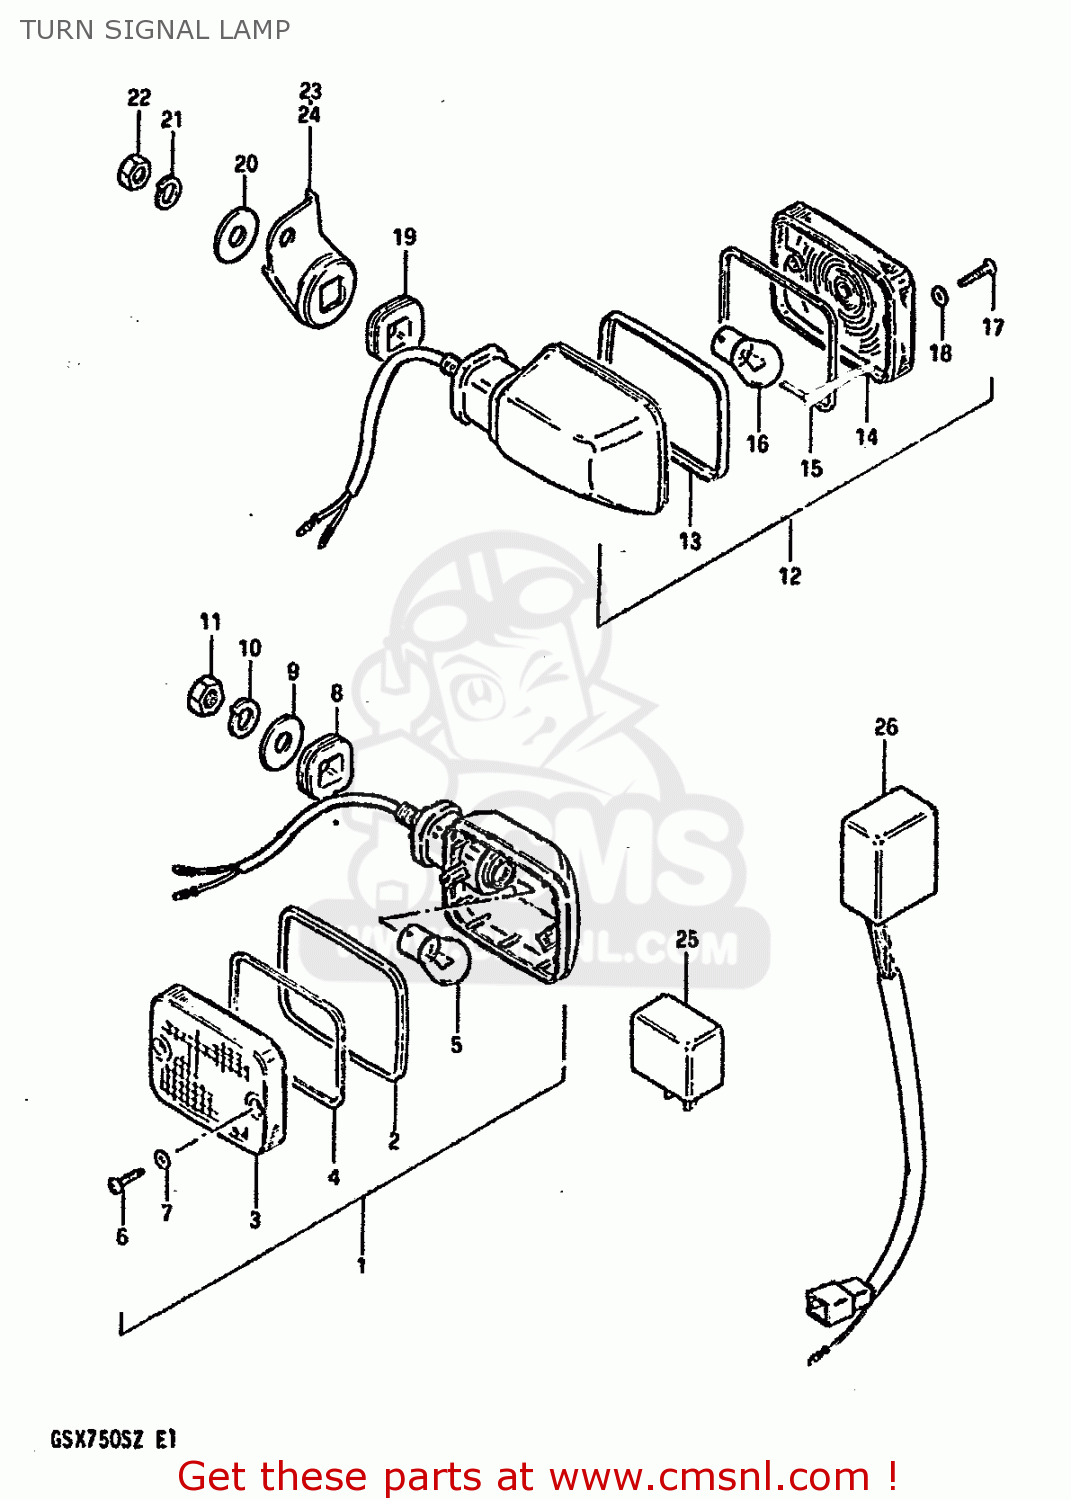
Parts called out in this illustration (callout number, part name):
1	LAMP ASSEMBLY,FRONT TURN SIGNAL
2	RIM
3	LENS
4	GASKET (NAS)
5	BULB(12V23W,STANLEY,A4577A)
6	SCREW
7	GASKET (NAS)
8	CUSHION
9	WASHER (10.5X30X2.3)
10	LOCK WASHER
11	NUT
12	LAMP ASSEMBLY,FRONT TURN SIGNAL
13	RIM
14	LENS
15	GASKET (NAS)
16	BULB(12V23W,STANLEY,A4577A)
17	SCREW
18	GASKET (NAS)
19	CUSHION
20	WASHER (10.5X30X2.3)
21	LOCK WASHER
22	NUT
23	BRACKET,RR TURNSIGNAL LAMP,R
24	BRACKET,RR TURNSIGNAL LAMP,L
25	RELAY ASSY,TURNSIGNAL
26	UNIT,TURN SIGNAL CONTROL
